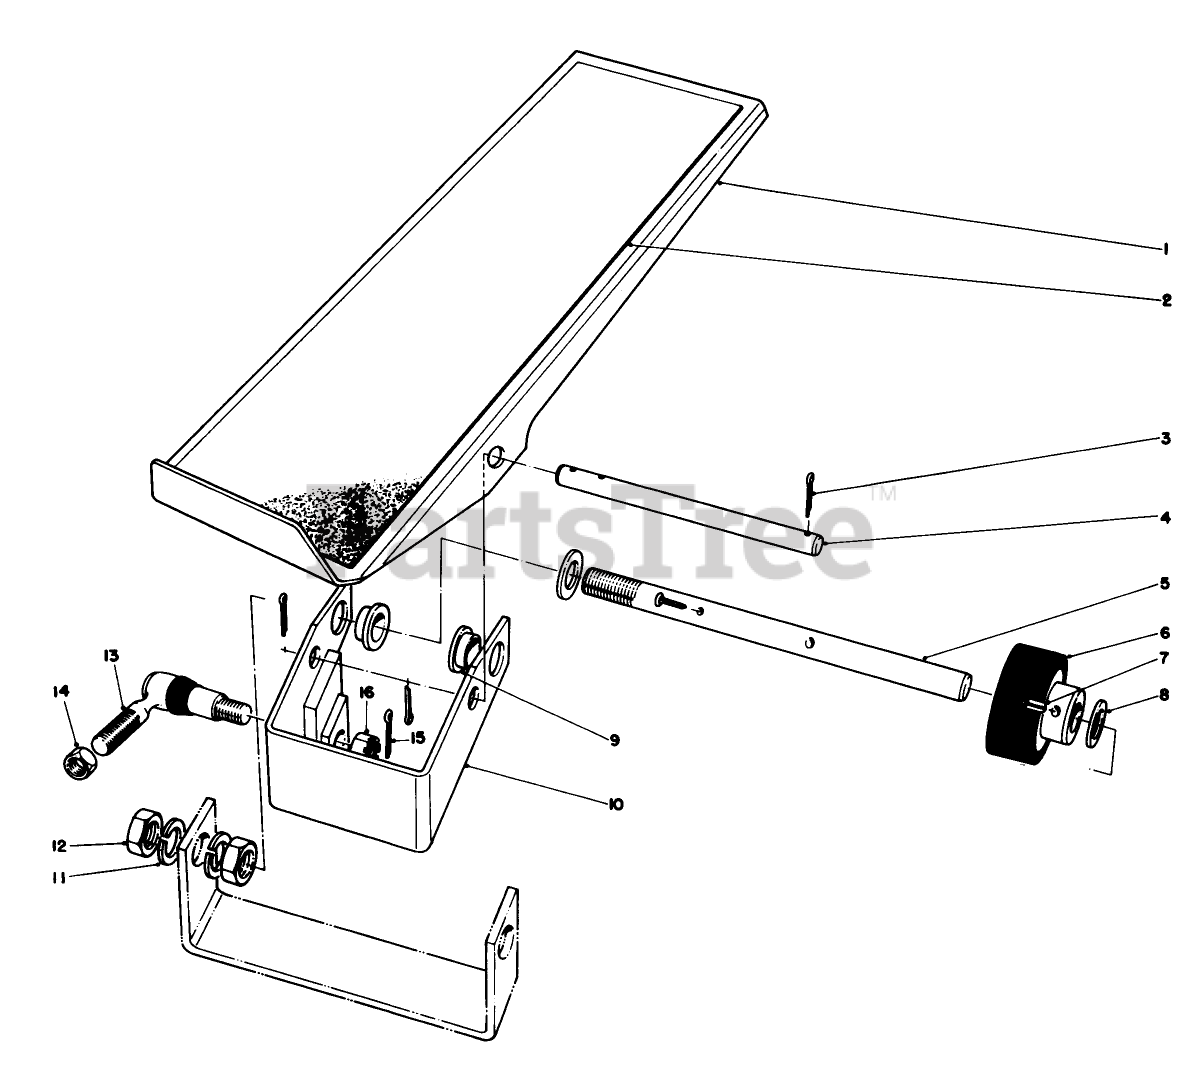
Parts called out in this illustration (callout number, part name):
1	Pedal-Traction
2	TRACTION PEDAL PAD
3	PIN-COTTER
4	PEDAL PIVOT PIN
5	Shaft-Traction Pedal
6	FRICTION WHEEL ASM
7	PIN-SPRING
8	WASHER-FLAT
9	BUSHING-FLANGE
10	Pivot Bracket Assembly (Incl. Ref. #9)
11	WASHER-LOCK
12	NUT-JAM
13	Socket
14	NUT-JAM
15	PIN-COTTER
16	NUT-SLOTTED
